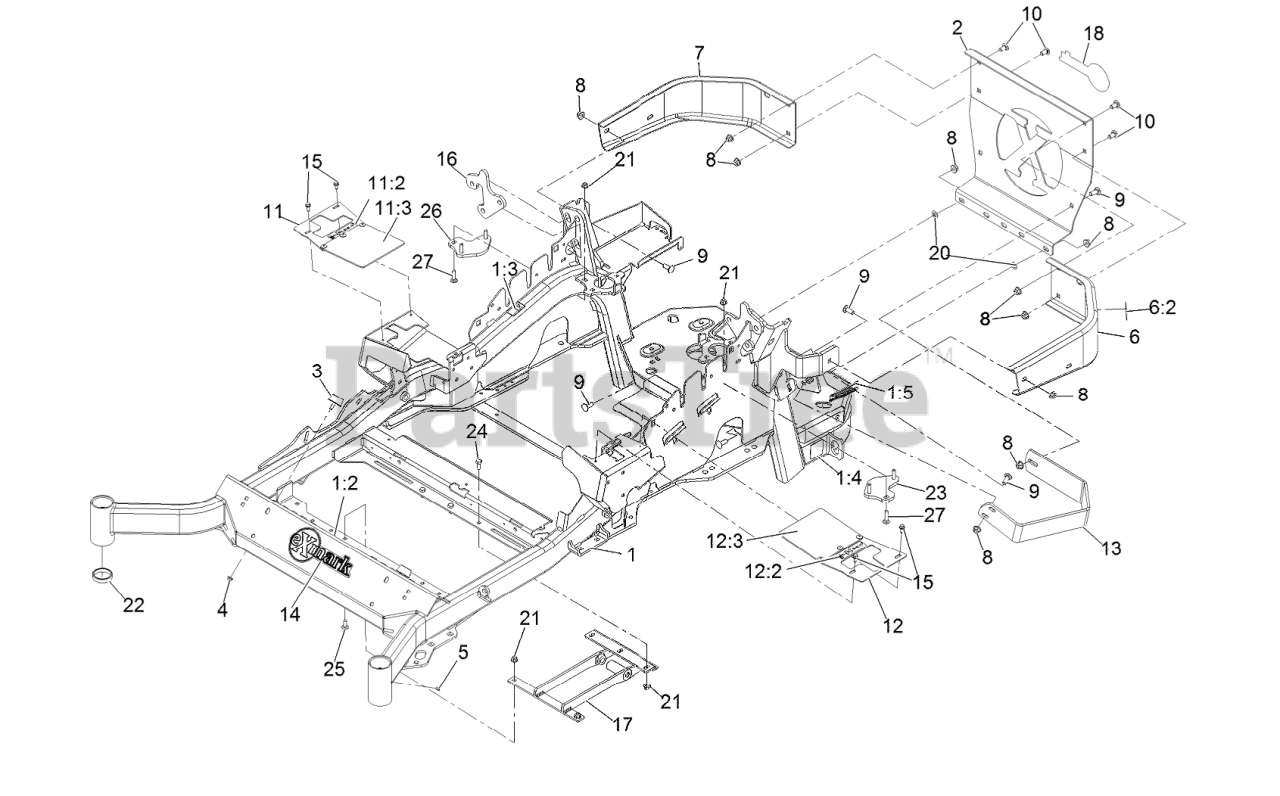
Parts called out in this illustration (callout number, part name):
1	MAINFRAME ASM
1:2	DECAL-DANGER
1:3	DECAL-WARNING
1:4	DECAL-HAZARD, PINCHED FINGER
1:5	DECAL-SPARK ARRESTER
2	PLATE,REAR GUARD
5	ASM,ROPS SERVICE EXMARK
7	Caster Wheel ASM
9	LH BUMPER ASM
9:2	DECAL-WARNING
10	BUMPER-RH
11	NUT-HF, NI
12	SCREW-CARR
13	SCREW-CARR
14	RH MOTION CONTROL COVER A
14:2	DECAL-CONTROL, MOTION
14:3	FLAP-RUBBER
15	LH MOTION CONTROL COVER A
15:2	DECAL-CONTROL, MOTION
15:3	FLAP-RUBBER
16	GUARD-MUFFLER
17	DECAL-EXMARK LOGO
18	SCREW-HWH
19	LH HYDRO GUARD ASM
19:2	DECAL-OIL, HYDRO
20	RH HYDRO GUARD ASM
20:2	DECAL-OIL, HYDRO
21	GUARD-HYDRO, REAR (LH)
22	GUARD-HYDRO, REAR (RH)
26	DECAL-X-SERIES
30	DECAL-EXMARK LOGO
33	RIVET-POP
34	DEFLECTOR-AIR FLOW
69	NUT-PUSH
76	DECAL-FUEL FILL, CE
77	CUP-BEARING
80	Decal-Patent Ttco.Com
81	WEIGHT-TOE BOARD
82	SCREW-HH
83	WASHER-FLAT
